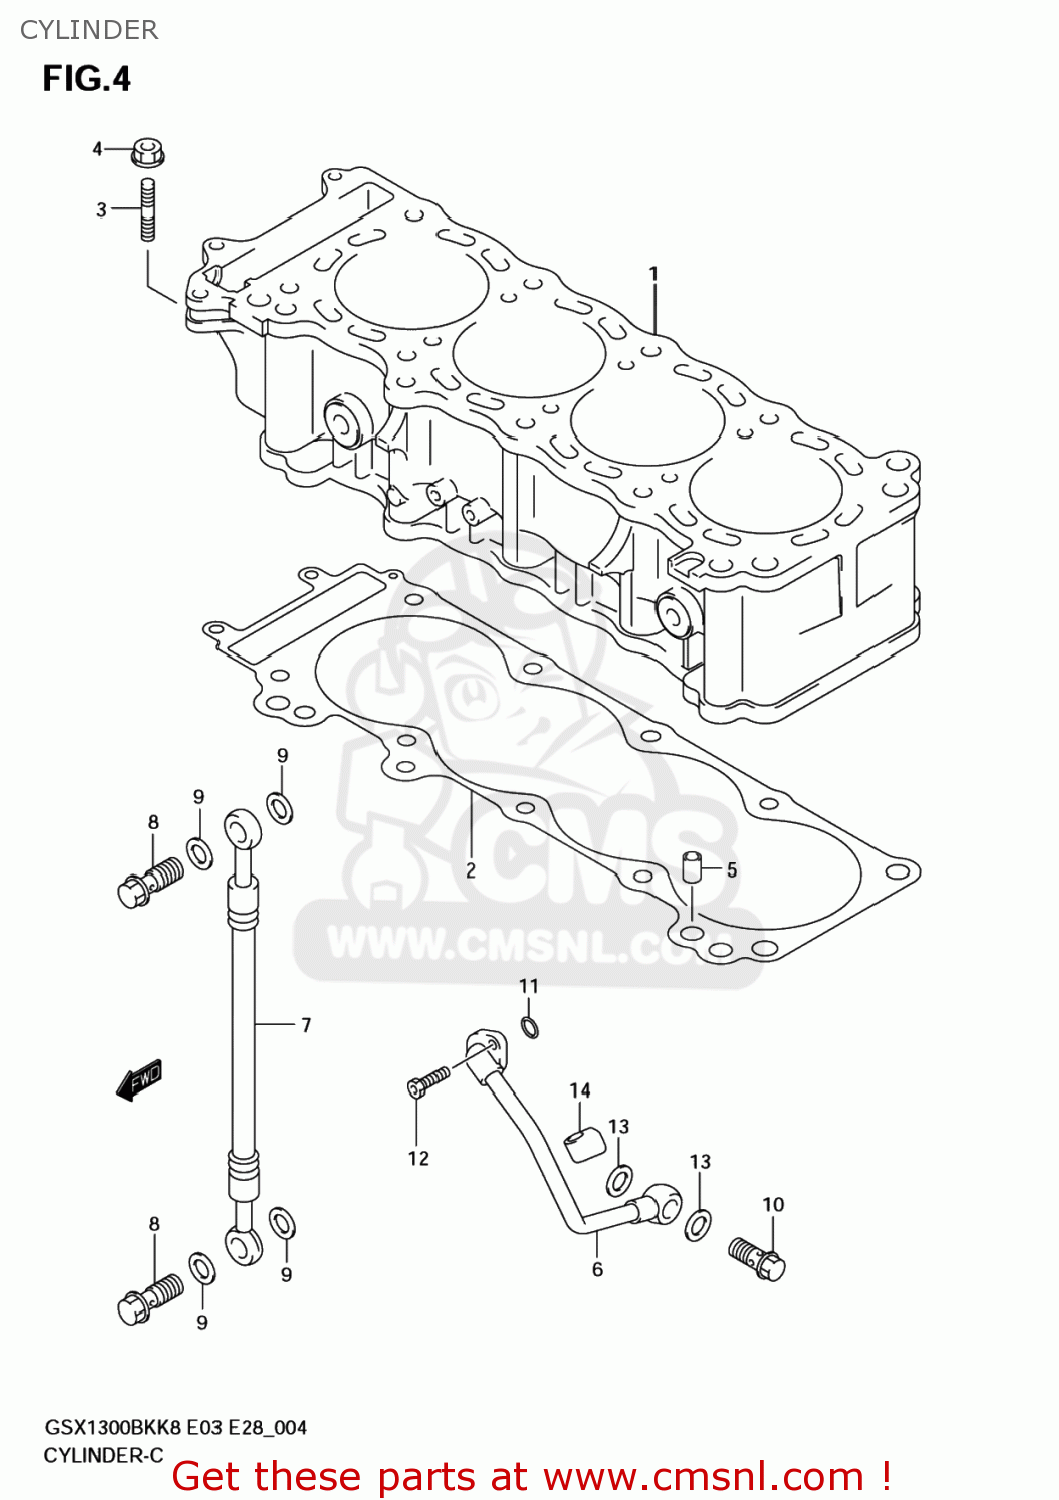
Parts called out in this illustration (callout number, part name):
1	CYLINDER
2	GASKET,CYLINDER (NAS)
3	BOLT,STUD
4	NUT
5	PIN
6	PIPE,CRANKCASE OIL
7	HOSE,CYLINDER HEAD OIL
8	BOLT UNION
9	GASKET(10.1X16X1) (NAS)
10	BOLT UNION
11	O RING(D:2.4,ID:11.8)
12	BOLT(6X16)
13	GASKET(14X20X1.5) (NAS)
14	CUSHION,CRANKCASE DIL PIPE
